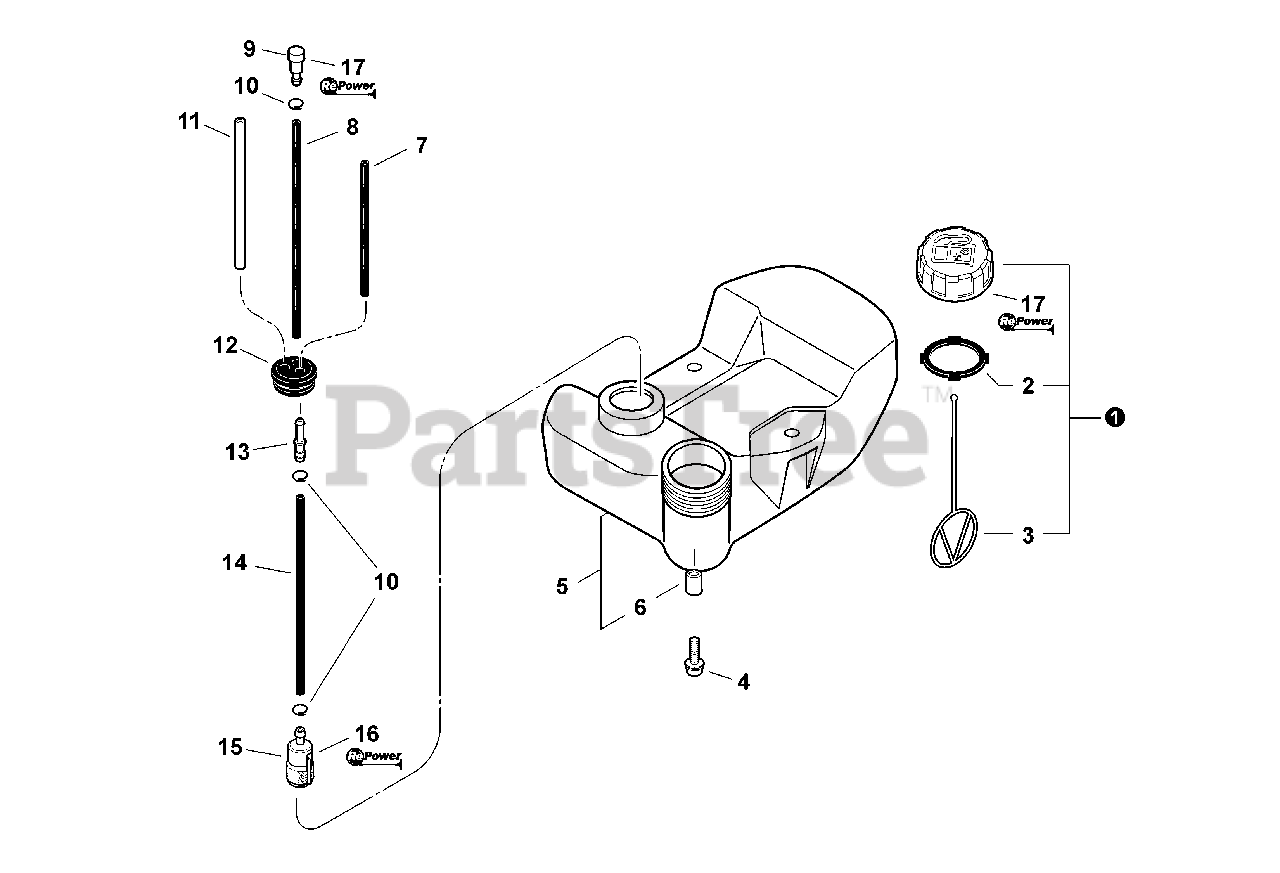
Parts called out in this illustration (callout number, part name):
1	CAP ASSY, FUEL
2	GASKET, FUEL CAP
3	CONNECTOR, CAP L= 100 MM
4	SCREW 5×16
5	TANK, FUEL
6	SPACER 6.2×7.8×6
7	PIPE, FUEL - 3×5×67 - BLACK
8	PIPE 3×6×115 BLACK
9	VENT ASSY
10	CLIP Ø6.5 MM
11	PIPE, FUEL 3×6×80 CLEAR
12	GROMMET, FUEL
13	CONNECTOR, PIPE Ø5ר3.5
14	PIPE, FUEL 3×6×110
15	FILTER, FUEL
16	TUNE-UP KIT - REPOWER
16	FILTER KIT - REPOWER
17	CAP/VENT KIT - REPOWER
